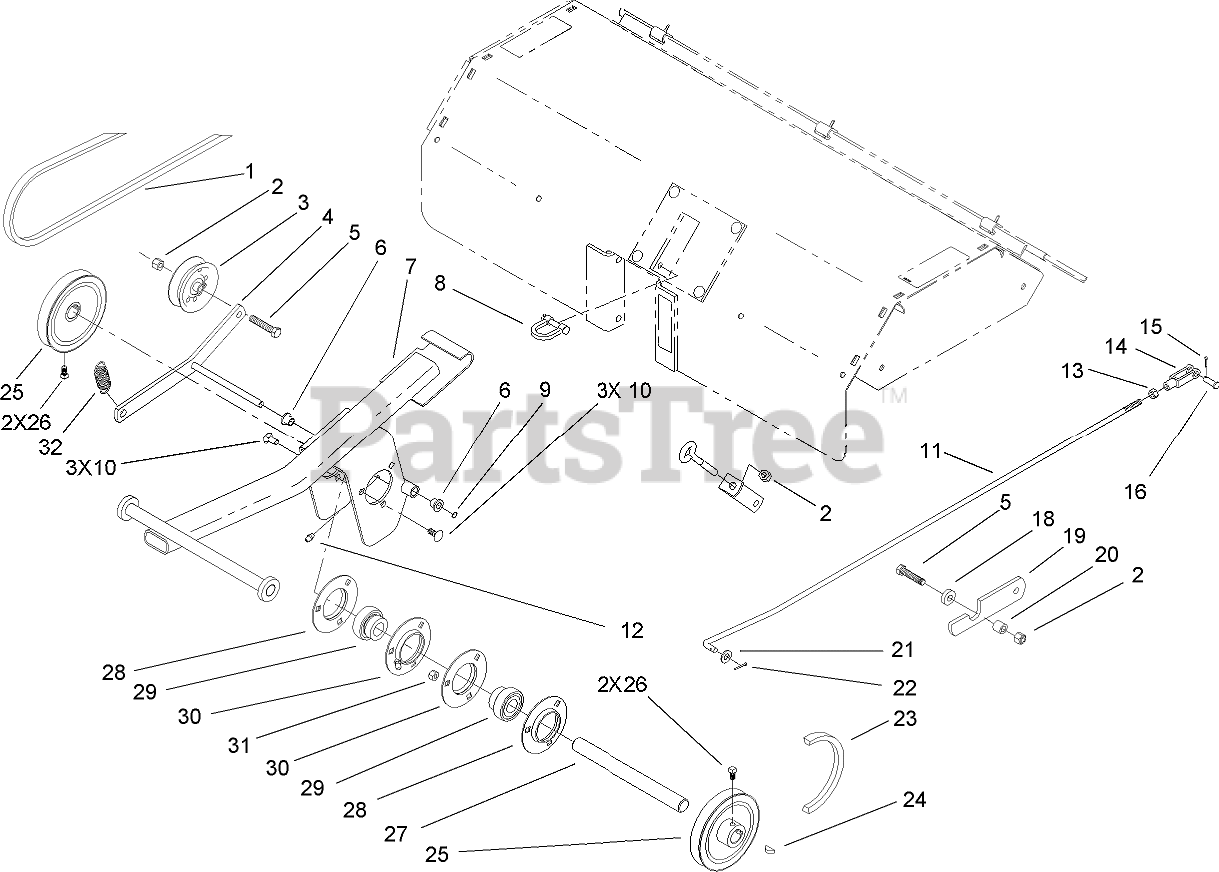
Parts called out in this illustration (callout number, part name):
1	V-BELT
2	NUT-LOCK, NI
3	PULLEY-IDLER
4	IDLER ASM
5	SCREW-HH
6	BUSHING-FLANGED
7	SUPPORT-JACKSHAFT
8	CLEVIS ASM
9	RING-RETAINING
10	BOLT-CARR
11	ROD-LIFT
12	FITTING-GREASE
13	NUT-HEX
14	YOKE-ADJUSTABLE
15	PIN-COTTER
16	PIN-CLEVIS
18	Washer
19	CATCH-SPRING
20	SPACER
21	WASHER-FLAT
22	PIN-COTTER
23	V-BELT, TRACTION
24	KEY-WOODRUFF
25	PULLEY-V
26	SCREW-SQH
27	SHAFT-JACK
28	Flange
29	BEARING AND COLLAR
30	FLANGE-ZERK RELUBE
31	NUT-LOCK, NI
32	SPRING-EXTENSION
